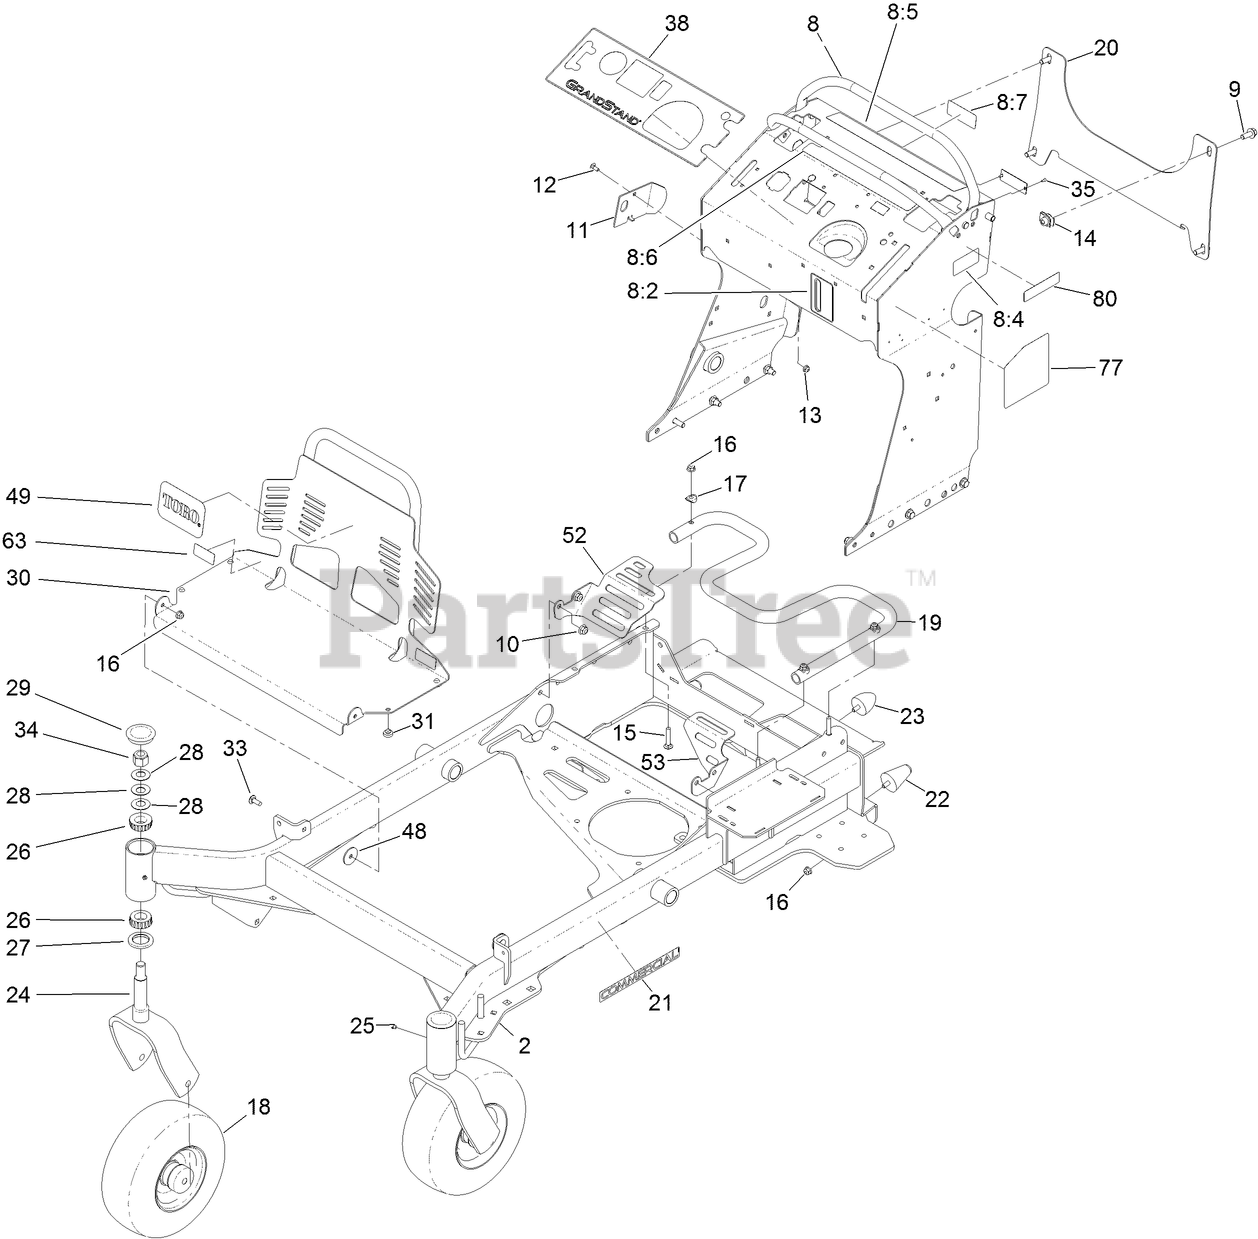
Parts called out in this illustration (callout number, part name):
8	TOWER DECAL ASM
8:2	DECAL-LEVEL, OIL
8:4	DECAL-FILL, FUEL
8:5	DECAL-CAUTION
8:6	DECAL-CONTROLS
8:7	DECAL-FUSE
9	SCREW-HHF
10	NUT-HF, NI
11	PLATE-STRIKER
12	SCREW-CARR
13	NUT-HF
14	NUT-TINNERMAN
15	BOLT-CAR
16	NUT-HF, NI
17	WASHER
18	WHEEL/TIRE AND BEARING ASM
19	TUBE-MOUNT, FUEL TANK
20	BRACKET-CROSS
21	DECAL-COMMERCIAL
22	BUMPER-RUBBER
23	BUMPER-RUBBER
24	FORK-CASTER
26	BEARING-ROLLER, TAPERED
27	SEAL-GREASE
28	WASHER-BELLVILLE
29	CAP-GREASE
30	GUARD-ENGINE
31	BUMPER
33	BOLT-CARR
34	NUT-LOCK, NI
35	RIVET-POP
38	DECAL-PANEL, CONTROL
48	WASHER-NYLON
52	GUARD-FAN, RH
53	GUARD-FAN, LH
63	DECAL-WARNING, NO RIDERS
77	DECAL-SERVICE AID
80	DECAL-ARRESTER, SPARK
